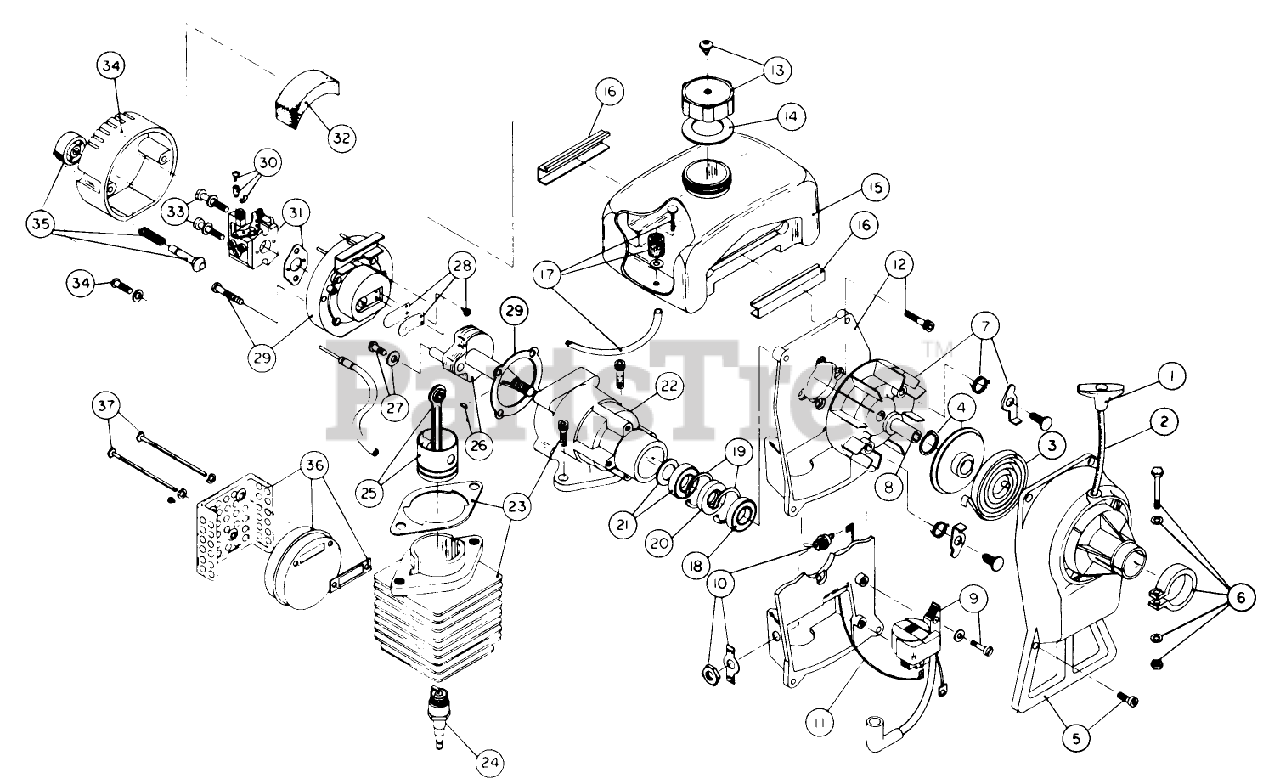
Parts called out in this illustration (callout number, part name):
8	SQUARE DRIVE NUT
10	SWITCH ASM
17	FUEL LINE ASM
18	OUTER BEARING
21	INNER BEARING ASM
24	SPARK PLUG
30	THROTTLE ADJ ASM
37	MUFFLER MOUNTING BOLTS
